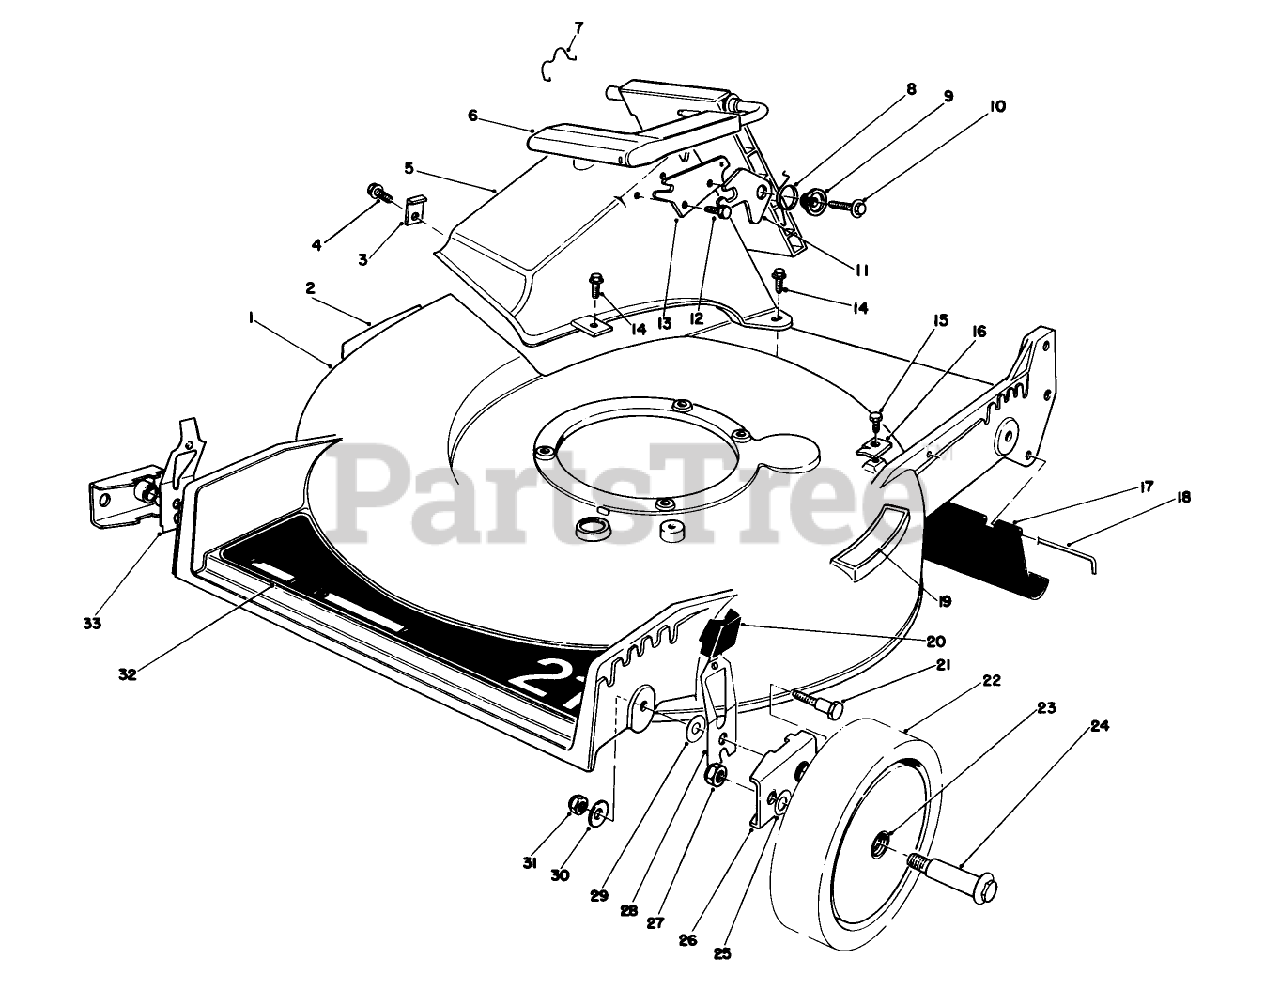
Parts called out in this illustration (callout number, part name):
2	DECAL-DANGER
3	TUNNEL CLIP
4	SCREW
7	DOOR RET SPRING
8	TORSION SPRING
9	DOOR SPACER
10	SCREW-HWH
11	SAFETY LATCH
12	SCREW-PLASTITE
13	DOOR LATCH PLATE
14	SCREW-HWH
15	SCREW-THD ROLL, HWH
16	CLAMP-CABLE
18	ROD-SHIELD
19	STEP PAD DECAL
20	KNOB-ARM
21	PIVOT SCREW
23	BUSHING
24	BOLT-WHEEL
25	WASHER
26	HP PIVOT ARM ASM
29	WASHER-PIVOT
30	WASHER-BELLEVILLE
31	NUT-LOCK, NI
